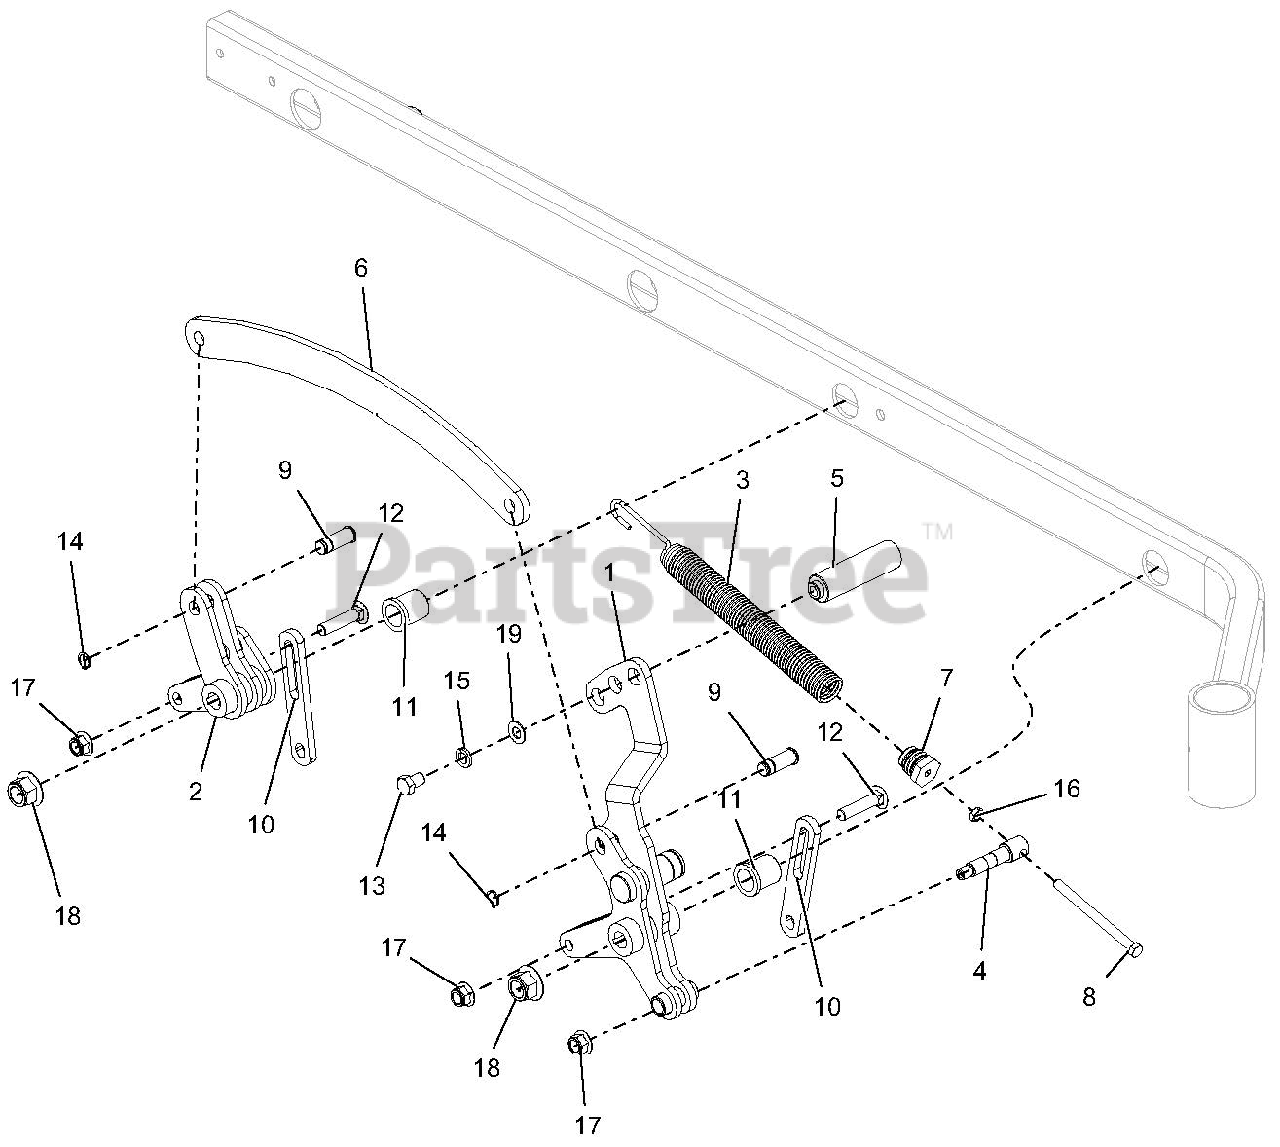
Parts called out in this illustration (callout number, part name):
1	WLDMT, PT400 FRONT RH DECK LIFT ARM
2	WLDMT, PT400 REAR RH DECK LIFT ARM
3	SPRG, DECK LIFT
4	TRUNION, SPRG
5	PEDAL, LIFT
6	LIFT, LINK
7	PLUG, SPRG
8	BLT-HEX .38-16X5.00 GR5 YWZC
9	PIN, CLEVIS .625 SNAP RING
10	LINK, DECK LIFT - LONG
11	BSHG-FLG 1.00X1.25X1.5X1.5
12	BLT-RDHDSQNK .50-13X2.25 G5 Y
13	BLT-HEX .50-13X.75 GR5 YWZC
14	RG-RTNG-EXT .625x.050
15	WSHR-LK .50X.125 REG YWZC
16	NUT, JAM .375-16 YWZC
17	NUT-LK-NYL-FLG .50-13 YWZC
18	NUT-LK-NYL-FLG .75-10 YWZC
19	WSHR-FL-STL .505X1.00X.062 YWZC
